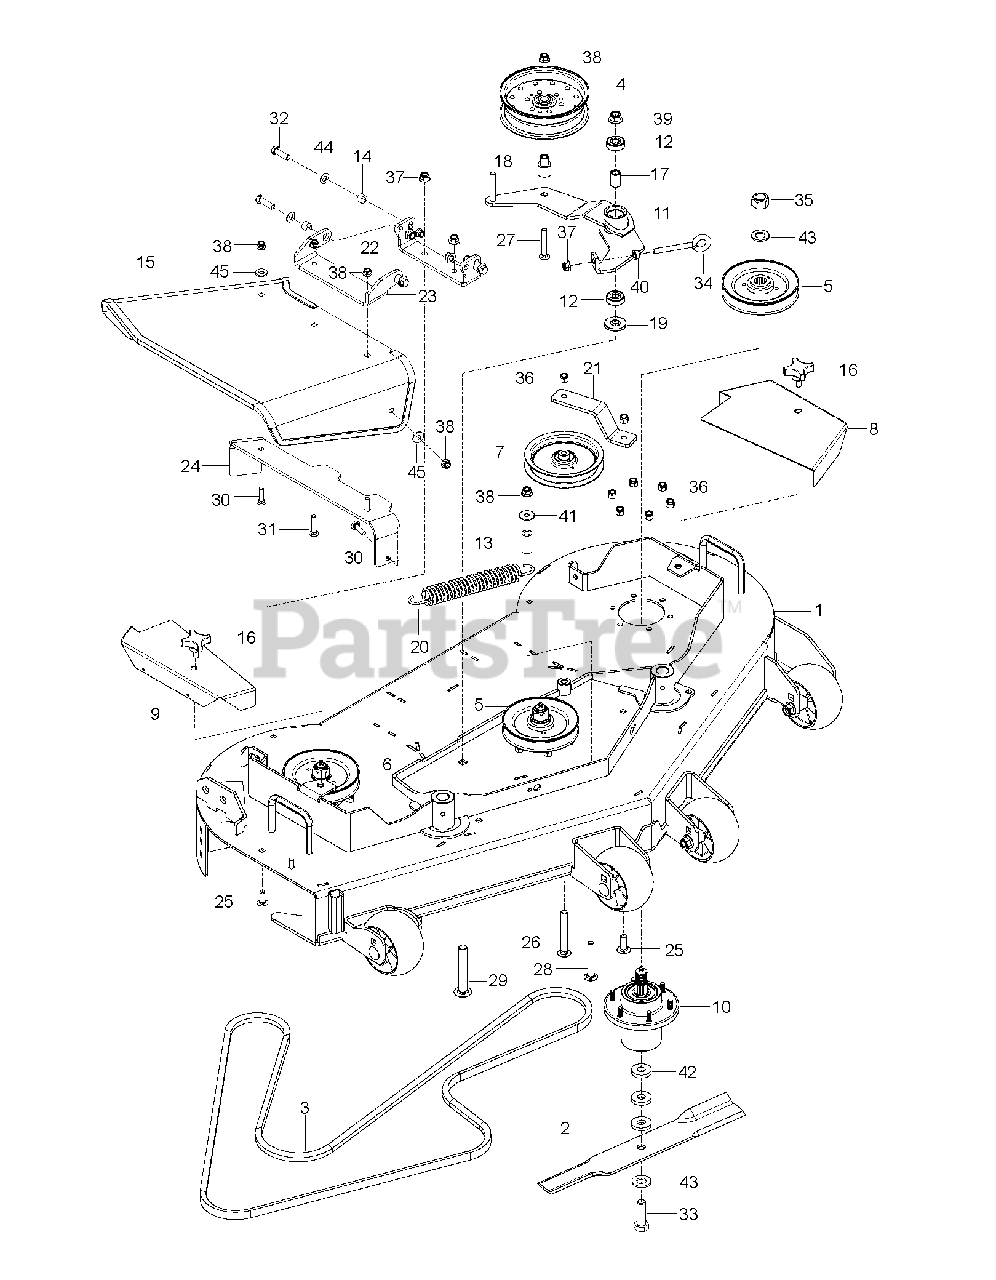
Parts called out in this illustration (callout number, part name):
2	Blade, 18 X .80 LI
3	BELT HB 131.0 EL AMD 181711
4	Flat Idler Pulley, 6.00 X .635
5	PULLEY SPINDLE 5.75 X .25 7344
6	PULLEY SPINDLE 5.75 X .76 7344
7	PULLEY FLAT IDLER 5.00X.75 733
8	SHIELD LH SPINDLE 52 FLWLK 511
9	SHIELD RH SPINDLE 52" FLWLK 51
10	Spindle Housing Assembly
11	ARM IDLER ARM 48 FLWLK WLDMT 4
12	BALL BEARING .500X1.38X.437 BA
13	BUSHING BSHG-SLV .500X.750X1.5
14	BUSHING BUSHING, SLV
15	CHUTE CHUTE, DISCHARGE RUBBER
16	KNOB KNOB, 3/8 -16 X .75
17	SPACER .510 X .75 X 1.1485 935
18	SPACER IDLER 4870200
19	SPACER IDLER ARM 4714600
20	SPRING SPRING EXTENSION .170X1
21	STRAP IDLER 48/52 WALK 3856447
22	BRACKET DISCHARGE PIVOT 510144
23	Discharge Mounting Bracket, LH
24	BRACKET BRACKET DISCHARGE 0478
25	BOLT BOLT RDHDSHSQNK .38-16 X
26	Round Head Bolt
27	Round Head Bolt
28	Round Head Bolt
29	Round Head Bolt
30	BOLT BOLT RDHDSQNK .31-18 X 1.
31	BOLT BOLT RDHDSQNK .31-18 X 1.
32	BOLT BOLT 3/8-16X1-1/4 HEX HEA
33	BOLT BOLT HEX .62-11 X 2.00 G
35	LOCK NUT LOCKNUT, 3/4-16 CROWN
36	NUT NUT, 3/8-16 NYLON LOCK ARI
37	NUT NUT, LK-NYL-FLG .38-16 YWZ
38	NUT NUT, LK-NYL-FLG .31-18 YWZ
39	NUT NUT, LK-NYL-FLG .50-13 YWZ
40	NUT .375-16 WHIZ LOCK FLANGE
41	WASHER WASHER, FL-STL .375 X 1
42	WASHER WASHER, FL-STL .630 X 1
43	WASHER WASHER, .75 X 1.3125 X
44	WASHER WASHER, FL-STL .406 X .
45	WASHER WASHER, FL-STL .38 X .8
